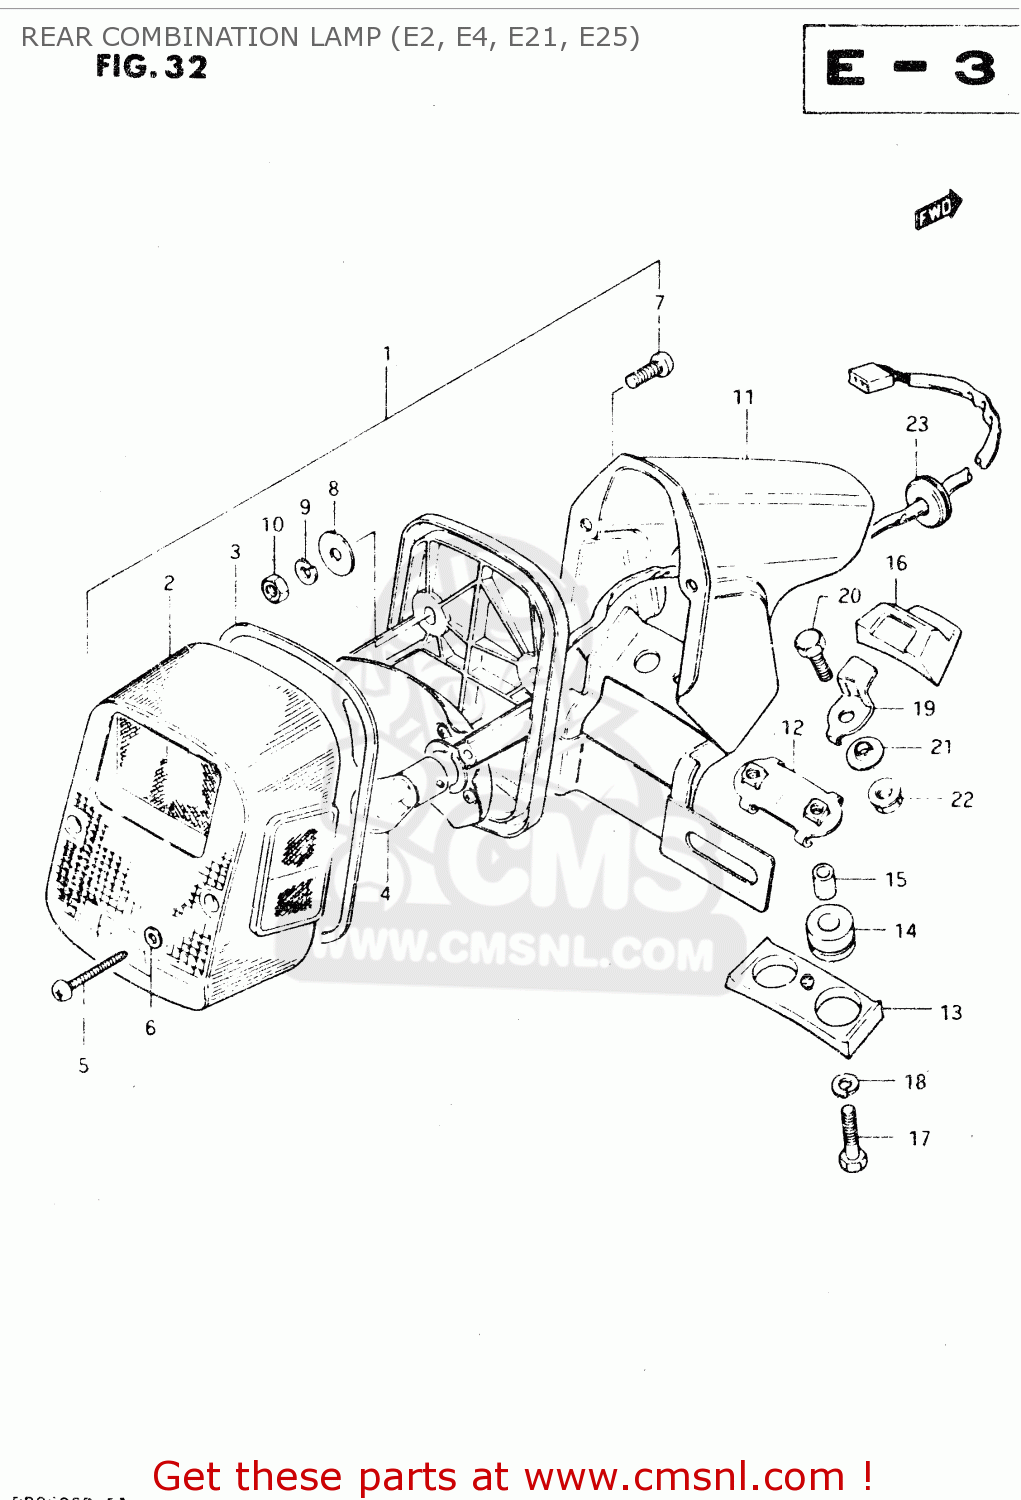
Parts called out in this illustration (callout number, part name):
1	LAMP UNIT, REAR COMBINATION
2	LENS,RR COMBI
3	GASKET (NAS)
4	BULB 12V21/5W
5	SCREW TAPP.
6	GASKET (NAS)
7	SCREW
8	WASHER,REAR COMBINATION LAMP
9	LOCK WASHER
10	NUT
11	BRACKET UNIT,TAIL LAMP
12	PLATE
13	CUSHION
14	CUSHION
15	SPACER
16	CUSHION,REAR COMBINATION LAMP
17	BOLT
18	LOCK WASHER
19	PLATE,RR COMBINATION LAMP
20	BOLT, UPPER
21	WASHER,LOCK
22	NUT
23	GROMMET
